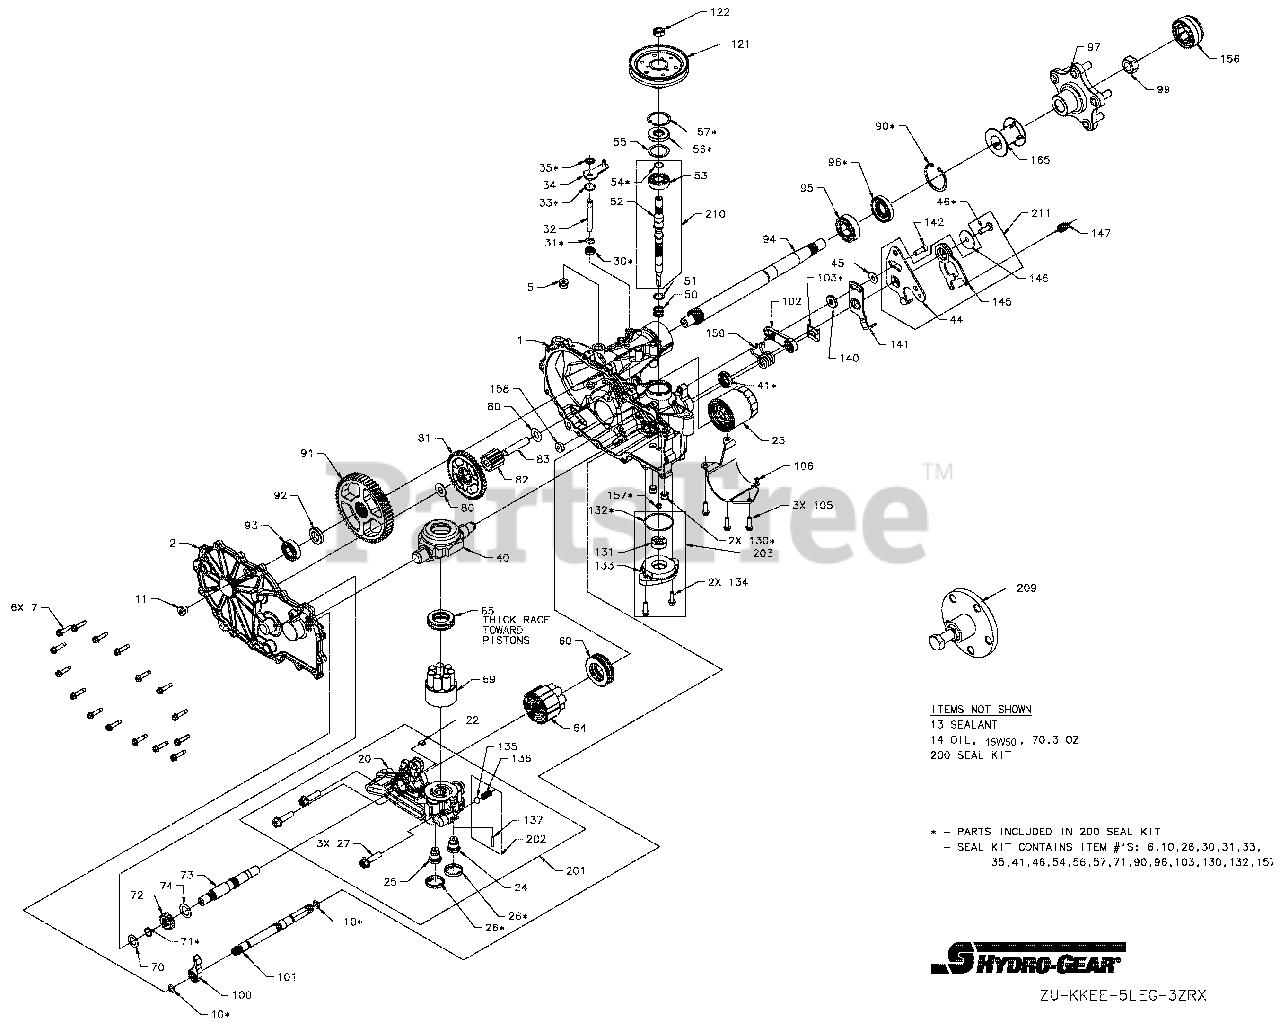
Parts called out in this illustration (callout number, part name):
7	HFHCS 1/4-20 x 1.125"
13	SEALANT
14	SYNTHETIC OIL, 15W50
22	PLATE, BYPASS
23	FILTER, OIL
26	SEAL, PLUG 1.250 x .250
30	SEAL, LIP .375 x .75 x .25
31	RING, RET .375 EXTRNL
33	RING, RET .750 INTRNL
34	ARM, BYPASS
35	RING, RTNG .375 EXT
40	TRUNNION, SWASHPLATE
41	SEAL, LIP 12 x 32 x 7
45	WASHER .34 x .88 x .06
46	TWHCS 5/16-24 x 1.00 (PATCH)
50	SPRING, BLOCK
51	WASHER-FLAT .59 x .79 x .04
55	WASHER 1.23 x 1.56 x .04
56	SEAL, LIP 17 x 40 x 7
57	RING, RETAINING
60	BEARING, THRUST
64	ASS'Y, CYLINDER BLOCK, 16cc
65	BRG, THRUST PLASTIC CAGE
69	ASS'Y, BLOCK 7 PISTON
70	WASHER .63 x 1.0 x .05
71	RING, RETAINING_.625
74	WASHER .72 x 1.16 x .04
80	WASHER .5 x 1.0 x .03
83	JACK SHAFT (PIN)
90	RING, RET 2.06 INT
95	BRG, BALL 25.4 x 52 x 15
96	SEAL, LIP 1.000 x 2.049 x .375
97	KIT, HUB, 5 BOLT
99	NUT, HEX LOCK 3/4-16
103	CLIP, RETAINING
106	GUARD, FILTER, LH
121	PULLEY, 4.5 x 1.625
122	NUT,HEX JAM 1/2-20 W/ PATCH
131	GEROTOR ASSEMBLY (1.9 cc/rev)
132	O-RING, -137, 0.103 x 2.050
140	SPACER .320 x 1.005 x .179
141	ARM, NEUTRAL LEFT
142	SHCS 5/16-24 x 1 PATCH
146	WASHER, .343 x 1.500 x .062
147	SPRING, EXTNSN RTN-34LBS
158	MAGNET, RING
200	KIT, SEAL
201	KIT, CENTER SECTION, LH, CHRG
203	KIT, CHARGE PUMP
210	KIT, INPUT SHAFT
211	KIT, RTN, CCW
